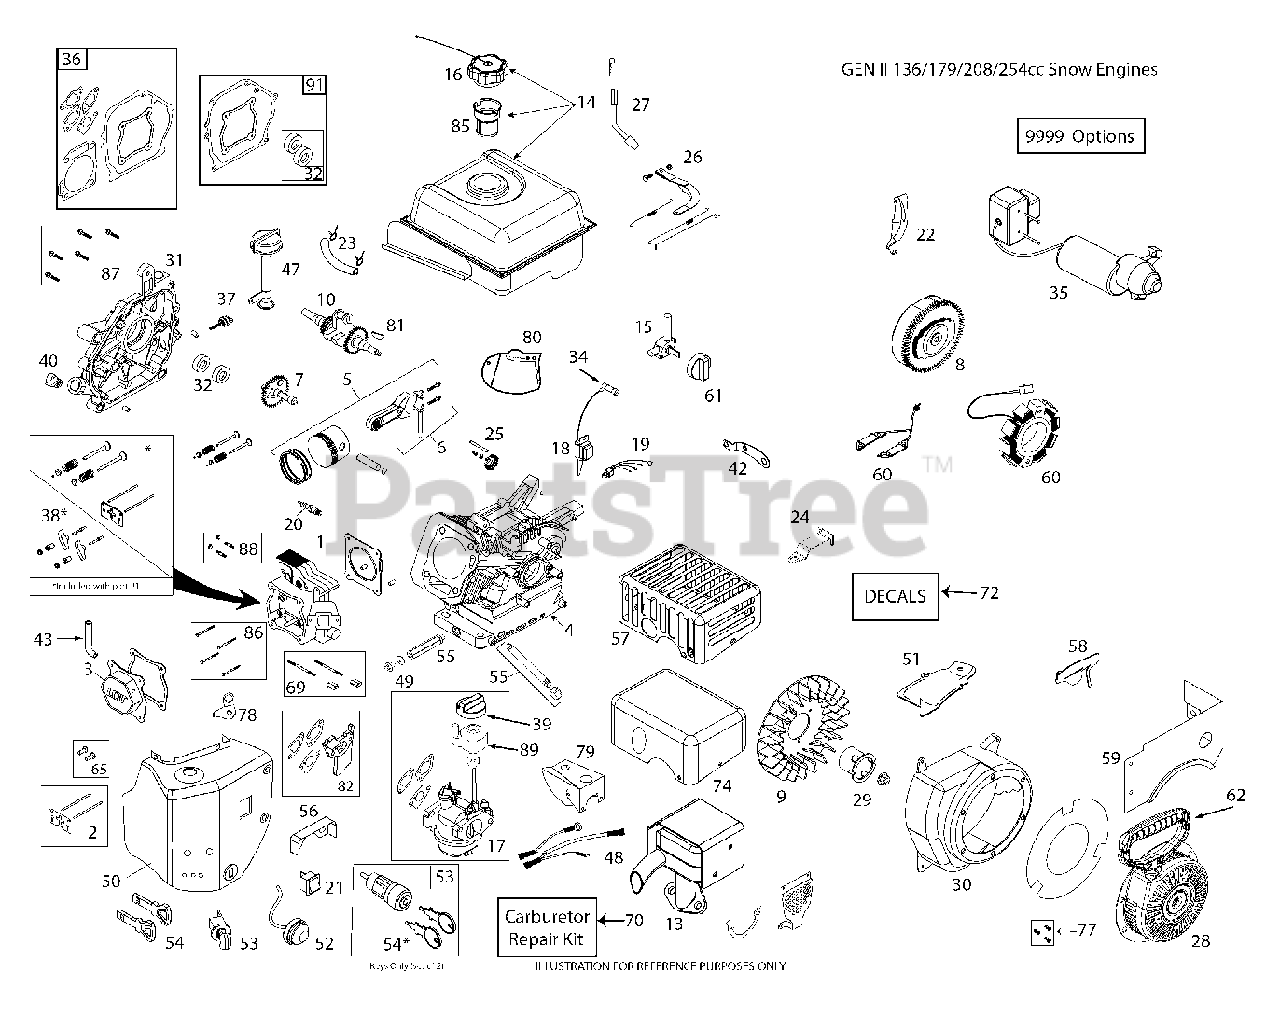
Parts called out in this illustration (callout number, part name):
2	KIT.PUSH.ROD.SRV(SK208-1001)
3	VALVE COVER ASSEMBLY
4	CYLINDER.ASM.SKSN0001.2
8	FLYWHL.ASSY.MANUL.SK2081700
9	KIT.COOLNG.FAN.SERV(SK208-4000
10	CRANKSHAFT KEYED LCT 179
13	ASSY.MUFFLER.GENII.SKSN0201.1
14	FUEL.TK.ASSY.GENII.SKSN0311.1
15	FUEL.PETCOCK.SNOW(SKSN4900)
16	FUEL CAP OVERSIZED CLICK STYLE
17	Carburetor, L10-1 LCT 208
18	CDI.BOX SNOW
19	Poulan TBD
20	SPARK.PLUG(2083810)
21	SWITCH.ON/OFF(SKSN-0403)
22	Poulan TBD
23	FUEL HOSE KIT
24	SPEED.CTRL.BRKT.(SKSN0150)
25	GOVENOR.GEARS ASM(SK2082900)
26	CARBURETTOR GOVERNOR LINK.ASM.
27	KIT.GOVERNOR.CRANK(SK208-3100)
28	RECOIL.STRT.ROUND(BLK) SNOW
29	STRTER.CUP(NON-SLOT)SKSN0601.2
30	BLOWER HOUSING ASSEMBLY
31	CRANKCASE.CVR.PRESS.IN.HI-OIL.
32	SEAL KIT (2 PCS)
34	SPARK.PLUG.BOOT.SNW,SKSN4691.1
35	Poulan TBD
36	GASKET KIT ENGINE LCT 208
37	DIPSTICK SMALL
38	ROCKER ARM KIT
39	CHOKE.KNOW.SNOW(SKSN4500)
40	NON REMOVABLE PLUG
42	Poulan TBD
43	TUBE.BREATHER.LCT.208
47	High Oil Fill Tube Assembly
48	Poulan TBD
49	KIT.OIL.DRAIN.PLUG(SK2089911
50	HEATER.BOX.ASY-GEN2
51	Poulan TBD
52	PRIMER.BULB.WITH HOSE (SNOW)
53	SWITH.KEY.ASSEM.SNOW.SINGLE.ST
54	KEY SET(2 KEYS) SKSN0407.1
55	EXTENDED OIL DRAIN TUBE
56	Poulan TBD
57	Poulan TBD
58	GOVERNOR.LINK.SHIELD PLATE
59	FUEL.TNK.SKRT.GENII.SKSN0103.1
60	Poulan TBD
61	FUEL KNOB-SNOW
62	Poulan TBD
65	TAPPET.KIT.LCT.208CC
69	CARB.STUDS & COUPLING KIT.SNOW
70	CARB.REPAIR.KIT.LCT.SK9900.1
72	Poulan TBD
74	COVER.MUFFLER.HEAT.SHIELD.
77	BOLT.KIT.RECOIL.LCT.ALL.ENGINE
79	COVER.CARBURETOR.SNOW
80	Poulan TBD
81	KEYS.FLYWHEEL.208/414CC.5PACK
82	SPACER.CARBURETOR.208CC.LCT
85	Fuel Tank Strainer, LCT 208cc
86	KIT.BOLT.CYLINDER.HEAD.(4PC)
87	KIT.BOLT.CRANKCASE.COVER.6PC
88	STUD.MUFFLER.KIT.LCT
89	Poulan TBD
91	Crankcase Cover Gasket
9999	High Altitude Jet for Beyond 6,000 Feet
